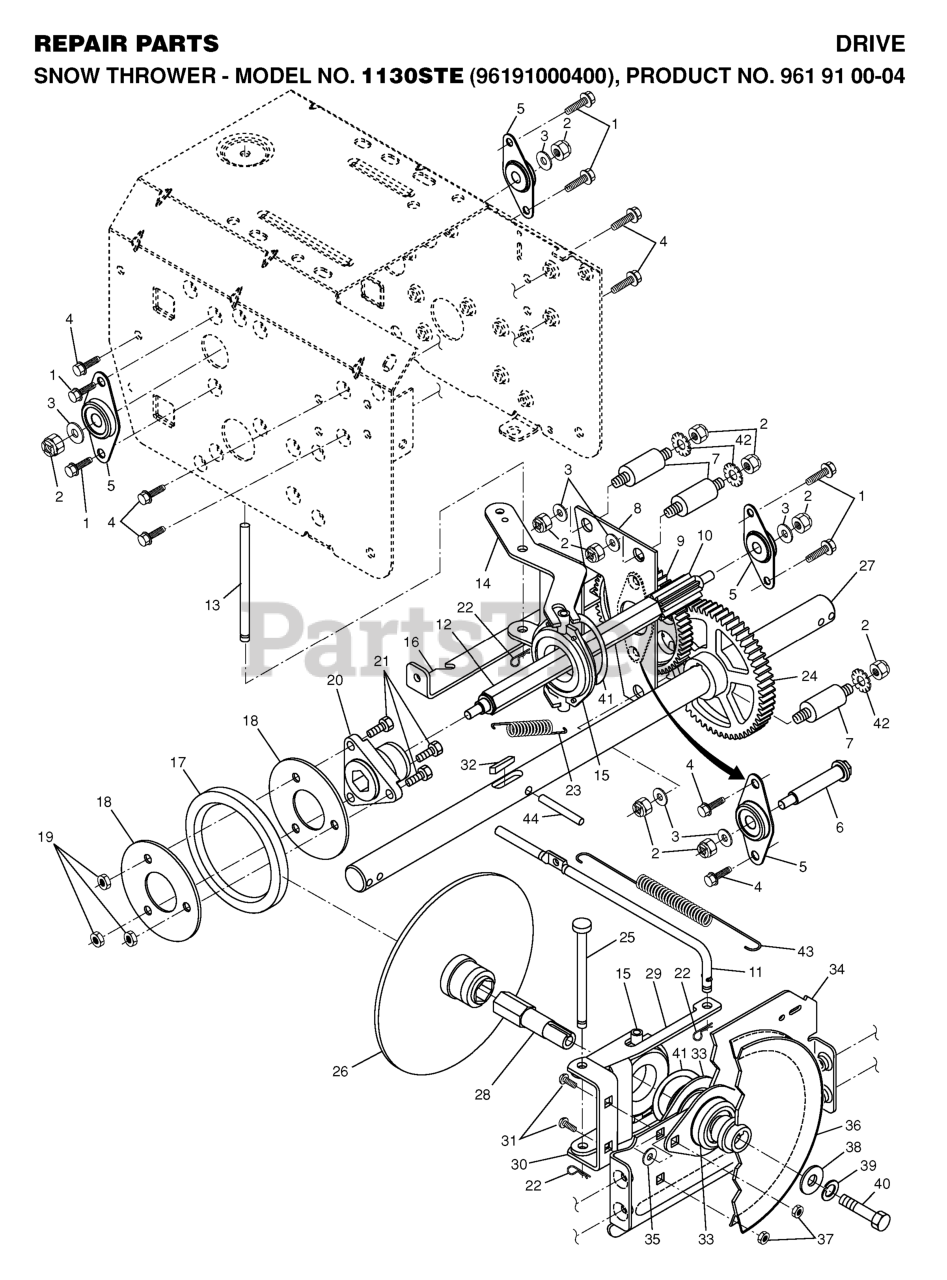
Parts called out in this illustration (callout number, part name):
2	NUT.71038.31-18.HEX.NYLOCK
3	WASHER.20X8.5
4	Screw 5/16-18 x 1/2 Hex, Self Tapping 5/16-18 x 1/2
5	BEARING, FLANGE
6	SHAFT, AUXILIARY
7	SPACER, PLATE
8	AUXILLARY PLATE
9	GEAR, INTERMEDIATE
10	GEAR, PINION
11	ROD.CLUTCH.YELLOW.ZINC
12	SHAFT.HEX.LONG
13	PIN, PIVOT
14	LEVER, SPEED CONTROL
15	TRUNNION BEARING ASSY
16	BRACKET, PIVOT, SHIFT
17	RING, RUBBER WHEEL
18	PLATE.RUBBER.WHEEL
19	NUT.CENTERLOCK.5/16-
20	HUB, RUBBER WHEEL
21	BOLT
22	RETAINER CLIP PM
23	SPRING, BIAS
24	GEAR, AXLE (58T)
25	PIN, PIVOT LEVER
26	DRIVE PLATE WELDMENT
27	SHAFT.AXLE.16".POWER.STEER.SNO
28	SHAFT.HEX.SHORT
29	LEVER.SHIFTER.PLATE.BLACK
30	BRACKET, SHIFTER SUPPORT
31	BOLT
32	KEY, SQUARE 1/4 X .875
33	BEARING FLANGE
34	PLATE.DRIVE.MOUNTING.BLACK
35	SPACER, BEARING
36	PULLEY.TRACTION.7.75
37	NUT.FLANGE.5/16
38	WASHER, FLAT
39	WASHER.LOCK.HVY.HLCL.SPR.5/16
40	Screw, Hex Head 5/16-18 x 3/4
41	RETAINING RING (2 2)(3 2)
42	WASHER EXT TOOTH LOCK 5/16
43	SPRING.RETURN
44	PIN.ROLL.3/16
